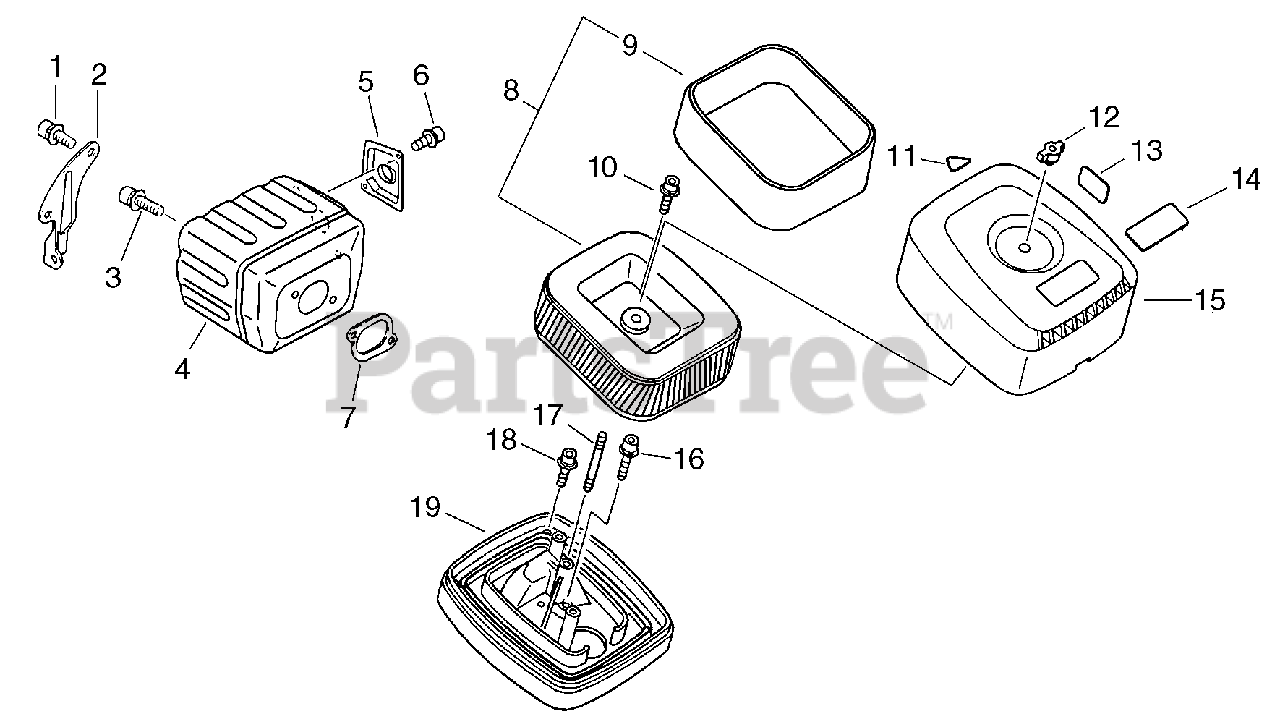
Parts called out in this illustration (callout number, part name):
1	BOLT 5×14
2	BRACKET, MUFFLER
3	BOLT 5×20
4	MUFFLER
5	GUIDE, EXHAUST
6	BOLT 4×10
7	GASKET, EXHAUST
8	FILTER, AIR
9	FILTER, AIR
10	BOLT - 5×16
12	NUT
13	LABEL, CAUTION
14	LABEL - MODEL CSG-680
15	COVER, AIR FILTER
16	SCREW 5×25
18	SCREW 5×16
19	CASE, AIR FILTER
